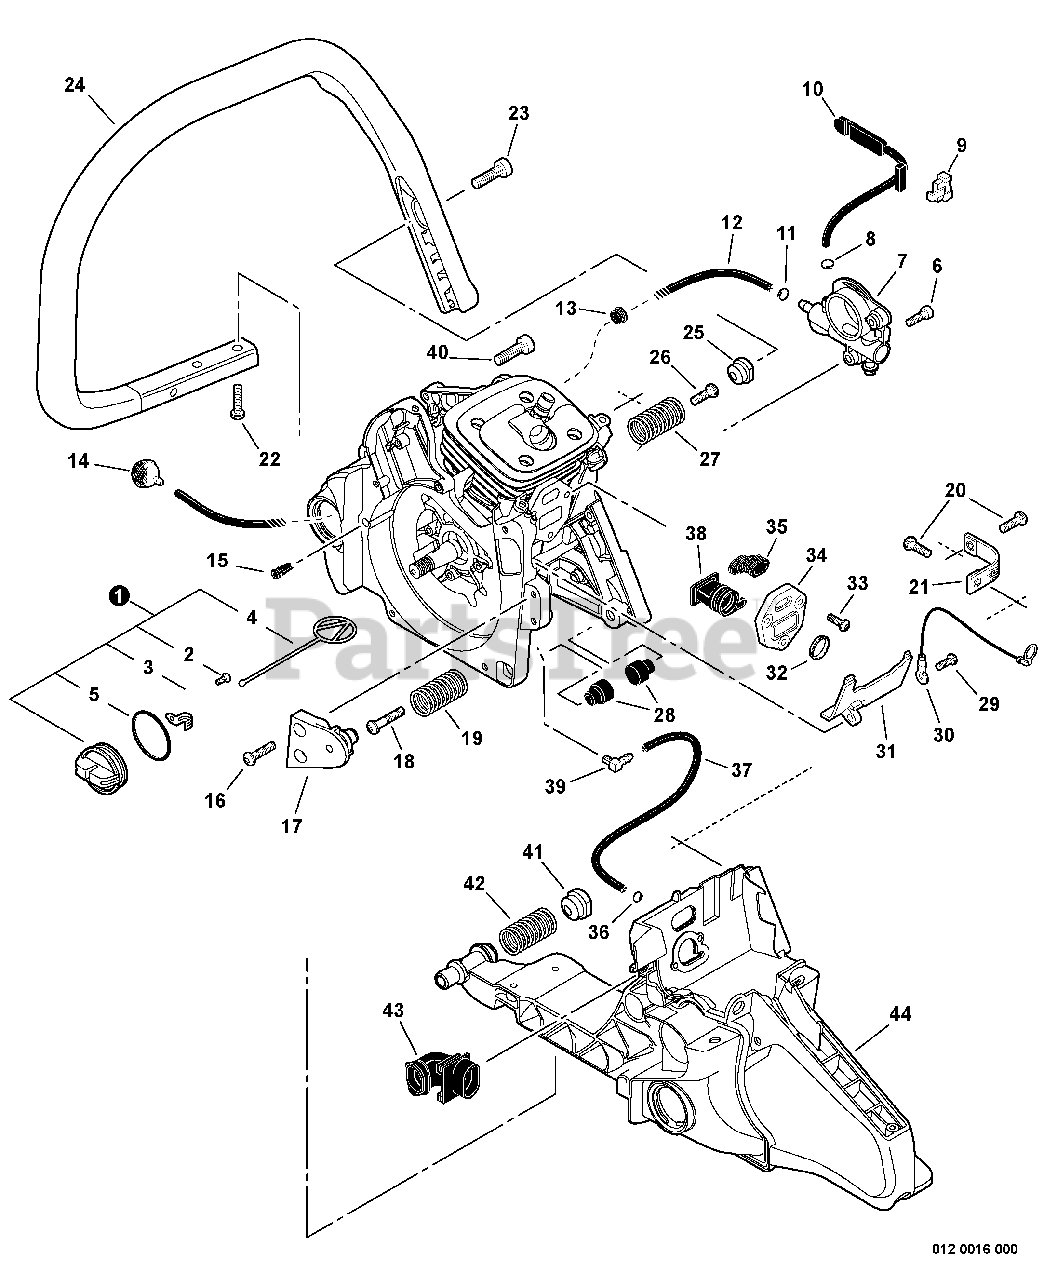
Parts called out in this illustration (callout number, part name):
1	CAP ASSY
2	SCREW - 3X8
3	RETAINER
4	CONNECTOR, CAP
5	O-RING - 28
6	SCREW - 4X12
7	AUTO-OILER ASSY
8	CLIP - 6
9	BRACKET
10	PIPE - OIL
11	CLIP - 6
12	PIPE - 3X6X210 -- BLACK
13	GROMMET
14	FILTER, OIL
15	VENT, TANK
16	SCREW - 5X20
17	HOLDER, SPRING
18	SCREW - 5X20
20	SCREW - 5X16
21	STRAP, SAFETY
22	SCREW - 5X20
23	SCREW - 6X20
24	HANDLE - FRONT
25	HOLDER, SPRING
26	SCREW - 5X16
28	CUSHION
29	SCREW - 5X16
30	LEAD - GROUND
31	GUIDE, AIR
32	COLLAR - 16
33	SCREW - 5X16
34	ADAPTOR
35	BELLOWS, INTAKE
36	CLIP - 6.5
37	PIPE - 3X6X120 -- BLACK
38	BELLOWS, INTAKE
39	FITTING, GREASE
40	SCREW - 6X20
41	HOLDER, SPRING
42	SPRING
43	DUCT, AIR
44	HANDLE - REAR
